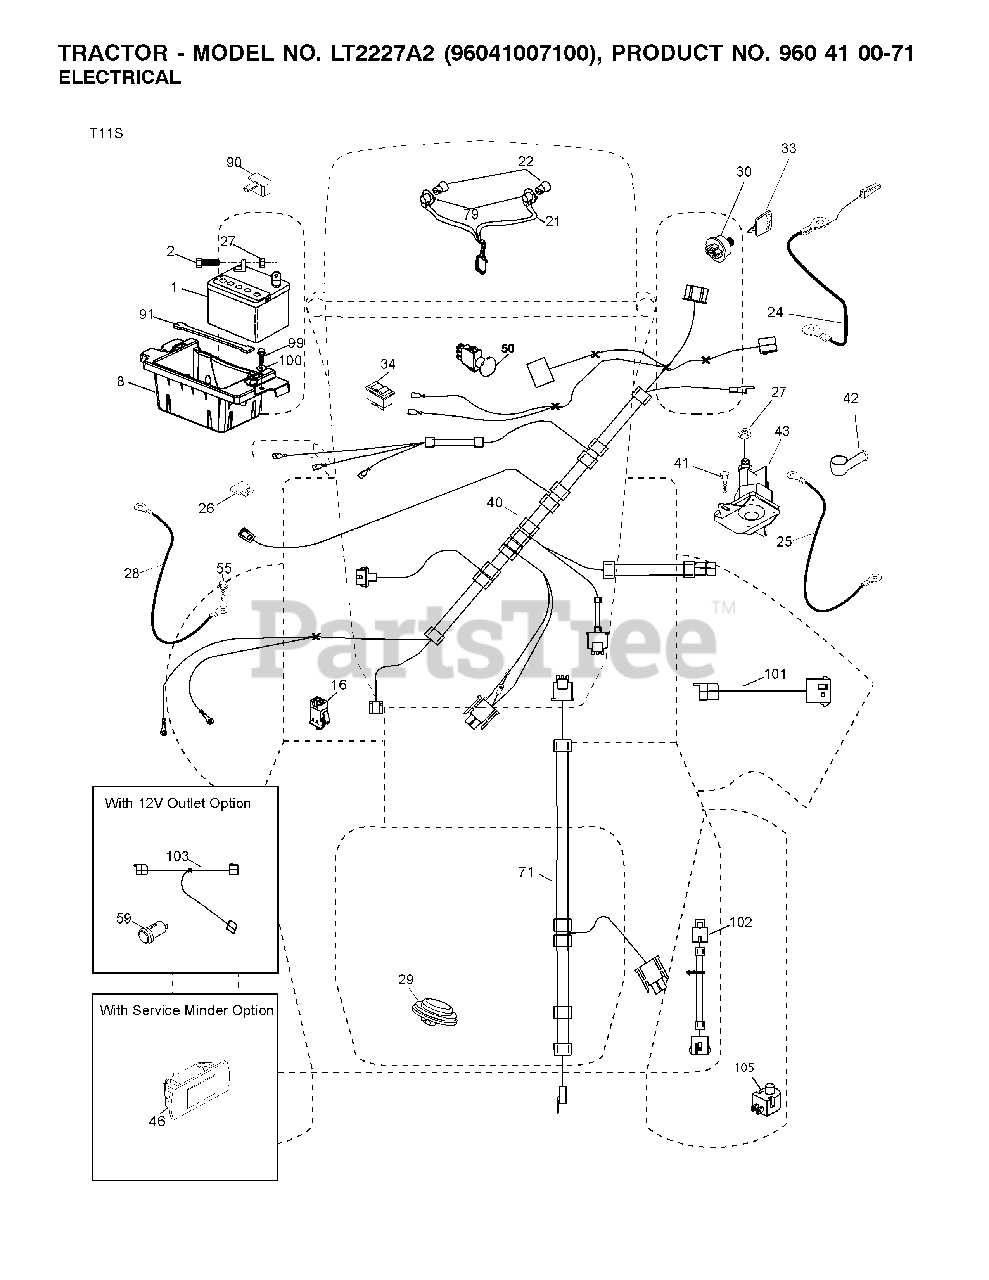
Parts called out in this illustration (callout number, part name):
1	BATTERY 12V .35 AMP
8	BOX.BATTERY.MOUNT.FRONT.LT
16	SWITCH INTERLOOK PUSH-IN
21	HARNESS.W/LIGHT SOCKET
22	LIGHTBULB
24	CABLE.BATT.POS.WIRE.TG.DA SOL
25	CABLE.START.RED.17.5".
26	FUSE 20AMP
27	NUT
28	CABLE GROUND 6 GA 21" 90T BLK
29	SWITCH.SEAT.DELTA.OPC.
30	SWITCH.IGN.DELTA.W.LGH.ROS
33	KEY.CHAIN.BLISTER.PACK.GEN.USA
34	SWITCH LT
40	HARNESS.IGN.DASH.HUQ/P
41	SCREW
42	TERMINAL COVER
43	SOLENOID.W/BRASS.PLUNG
46	GUAGE.SRVCMNDR.HRMTR.
50	PTO SWITCH
55	SCREW 5/16"
71	HARNESS-CHASSIS SUB
79	BULB HOLDER ASM.
90	COVER.TERMINAL.BATTERY
91	STRAP, BATTERY MOUNT
99	SCREW HEXWSHR 1/4-20X3/4
101	PIGTAIL.MATNLK.NEW.HAR
102	HARNESS PIGTAIL PCH TEX ROS
105	REVERSE SWITCH
